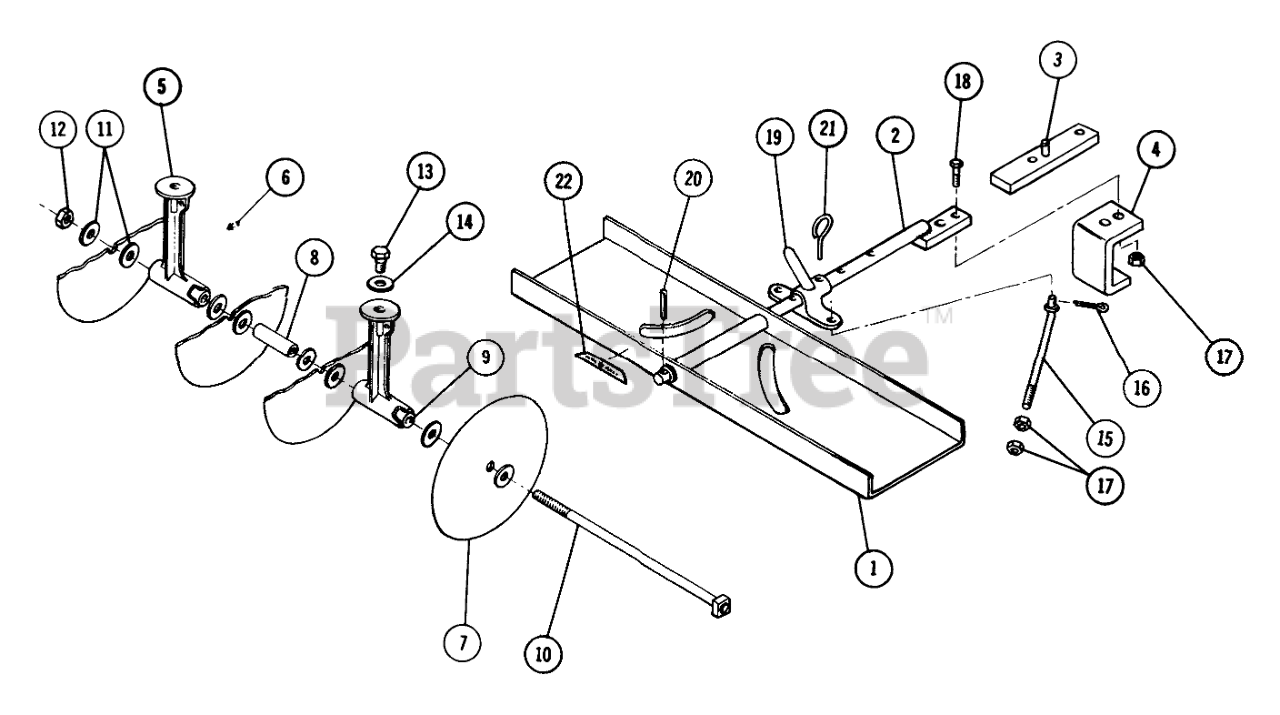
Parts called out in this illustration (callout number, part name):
1	Channel
2	Hitch Bar
3	Pivot Bar
4	Clevis-Disc Hitch
5	Gang-Disc
6	Zerk
7	BLADE DISC
8	Spacer
9	Tube
10	Bolt
11	Washer
12	E.S. Nut 3/4-10
13	Bolt Shoulder 5/8-11
14	Washer 7/8 SAE
15	Pivot Rod
17	Eslok Nut
18	H H C S
19	Blade Adjustment Lever
20	PIN-ROLL 1/4 X 1 1/4
21	Lever Lock Pin
22	DECAL-WHEEL HORSE
